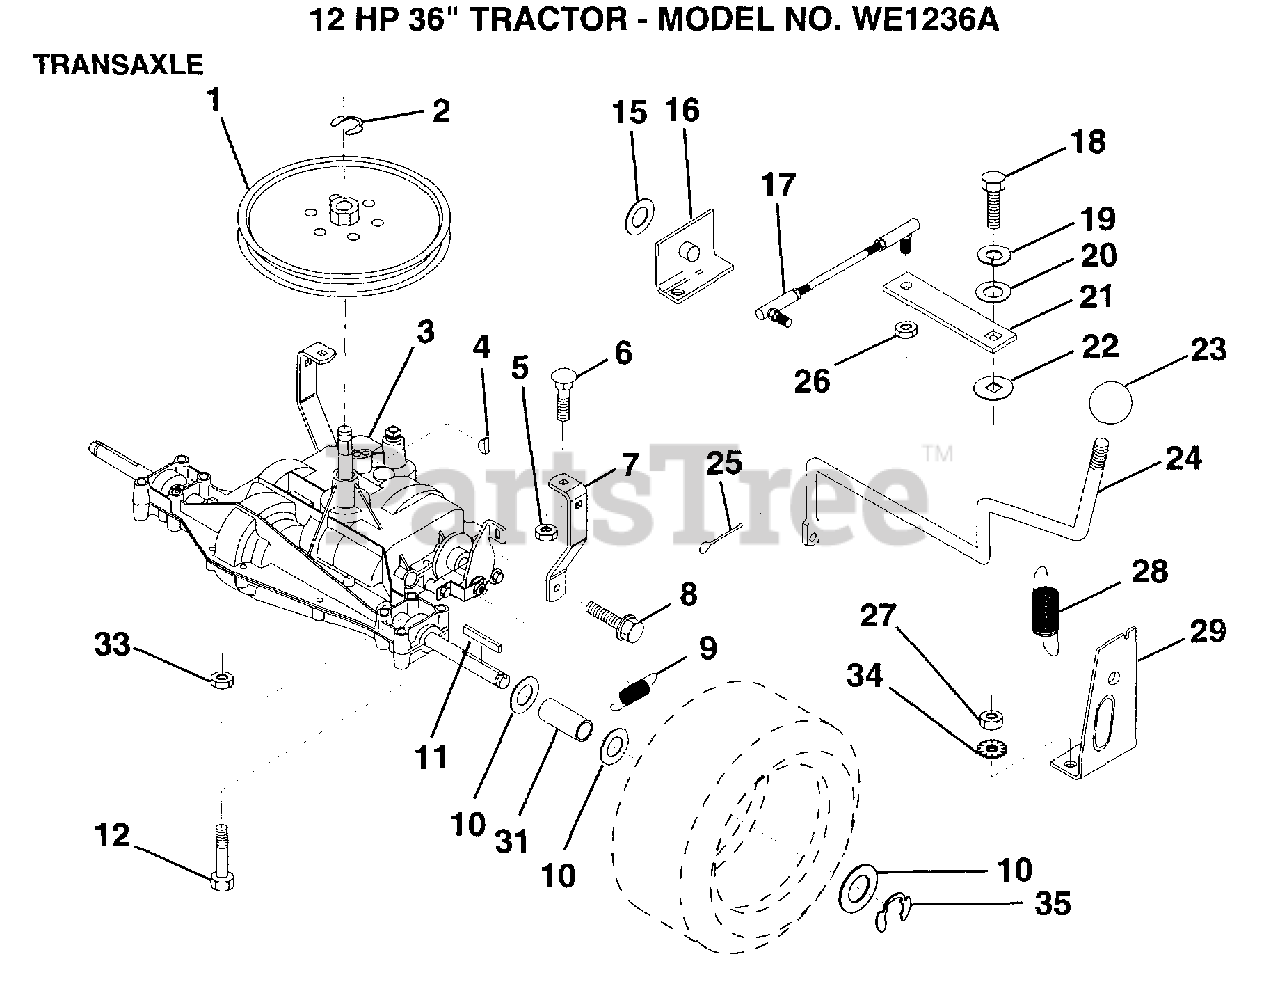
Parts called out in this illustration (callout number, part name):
1	PULLEY
5	NUT
6	BOLT
7	"STRAP,TORQUE"
8	SCREW
10	WASHER
11	SQUARE KEY
12	BOLT
16	"SUPT,HDLE SHT LH"
17	"LINK,SHIFT"
19	LOCKWASHER
20	WASHER LT
21	"ARM,SHIFT"
22	WASH-SHFT PLT LT
23	KNOB T (1/2-HOLE)
24	"ROD,SHIFT"
25	PIN COTTER 1/8
26	NUT.LOCK.5/16-24
28	"SPRING,EXT"
29	"SUPT,HDLE RH"
31	SPACER LT
33	NUT
34	LOCKWASHER.5/16.E
35	E-RING LT
